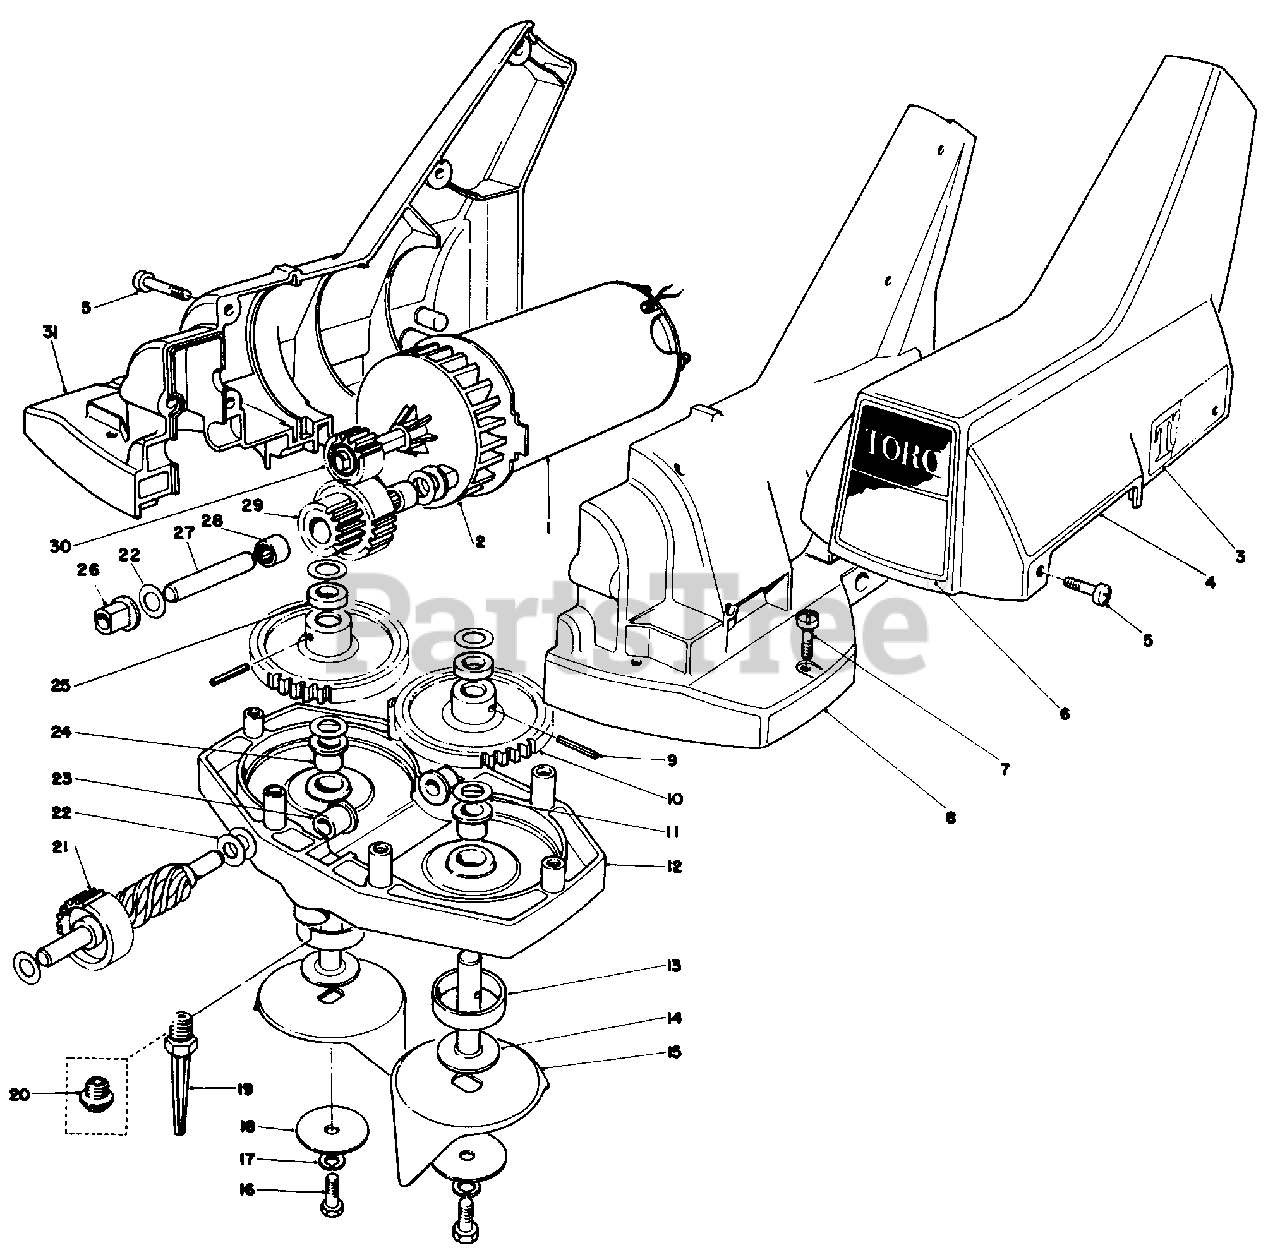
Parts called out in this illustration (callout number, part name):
1	Motor (Incl. Ref. #2 & 30)
3	Decal-Toro
8	Upper Case L.H.(Incl. Ref. #24)
10	Helical Gear
11	Thrust Washer
12	Lower Case (Incl. Ref. #24)
14	Tine Shaft
15	Tine Cup
16	Capscrew
17	Lockwasher
18	Washer
21	Worm Shaft w/Gear
22	Thrust Washer
27	Idler Shaft
29	Cluster Gear
30	Driver Gear
31	Upper Case R.H. (Incl. Ref. #24)
